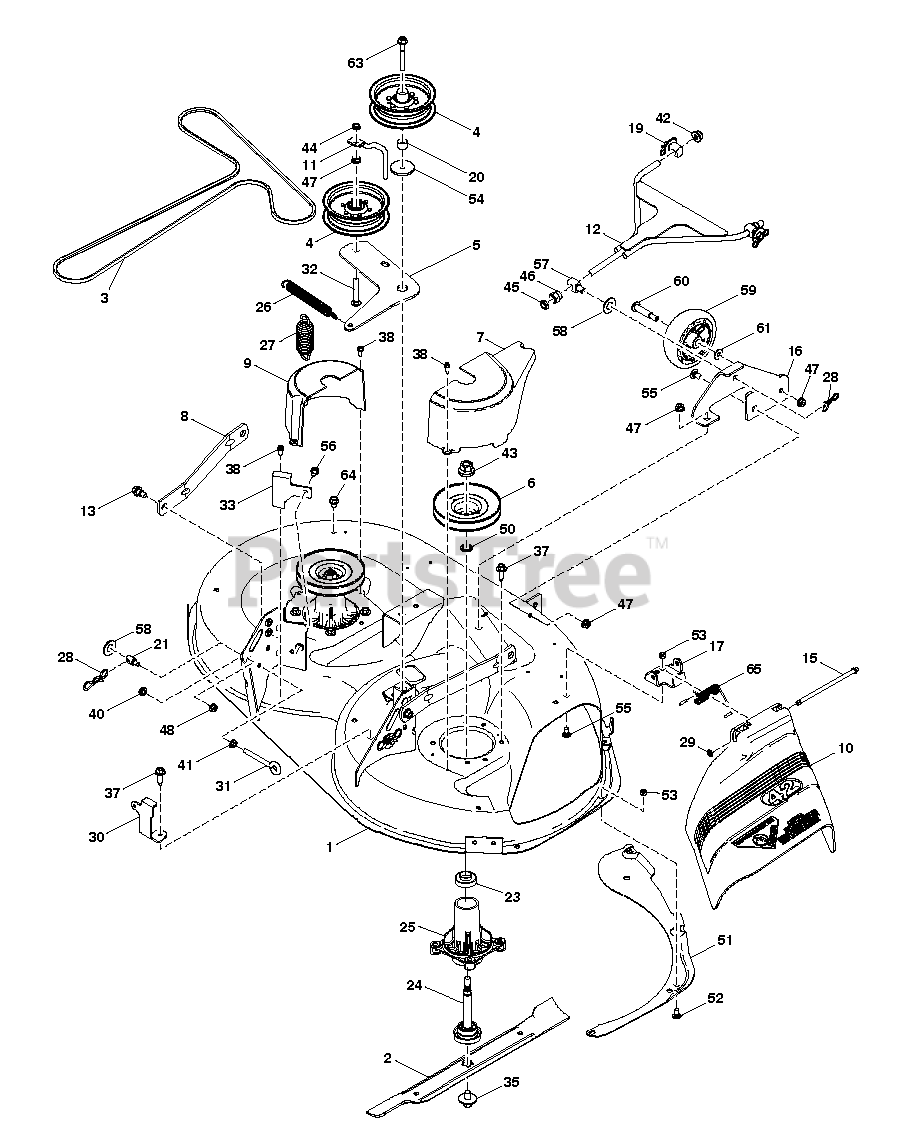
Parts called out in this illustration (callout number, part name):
1	KIT.42"DECK.W/DECALS.X668
2	42" HI-LIFT BLADE
3	BELT 42 STAMPED RZ DECK DRIVE
4	PULLEY.IDLER.2006
5	ARM 42 STAMPED RZ CLUTCHING AR
6	PULLEY.MANDREL.46"
7	COVER 42 STAMPED RZ RH MANDREL
8	ARM.RFIXED.MOWER.SUSPNSIONX431
9	COVER 42 STAMPED RZ LH MANDREL
10	SHIELD.DEFLECTOR.MOWER.42"BLAC
11	KEEPER.BELT.IDLER.54"T
12	LINK.RZ.FRONT.WELDMENT.E-DIP
13	SB 3/8-16 X 3/8 SKT HD ZD
15	ROD.HINGE
16	BRACKET.FRONT.SUSPENSION.X668
17	BRKT.DEFLECTOR.38"2005+
21	STUD.FASTNER.W/ANTI-ROTATE
23	BEARING.MANDREL.TOP.EXTENDED
24	SHAFT
25	HOUSING, MANDREL 48"
26	SPRING.MOWER.DRIVE.ELECTRIC
28	PIN.COTTER.5/16.BOW TI
29	NUT PUSH M
30	BRCKT.REAR.DECK.UPSTOP.RH.X668
31	EYE BOLT 5/16 X 3.50
32	CARRIAGE BOLT 3/8-16 X
33	BRCKT.REAR.DECK.UPSTOP.LH.X668
35	SCREW.SEMS.7/16-20X1.HEX.HEAD
37	BOLT.HEX.WASHR.HED.313-18X1.19
38	SCREW.1/4-20X5/8
40	NUT 5/16C WHIZ
41	5/16-18 NYLOC FLANGE NUT
42	7/16-14 HEX NUT W/NYL RING ZD
43	NUT.FLANGE.LOCK.TOP
45	NUT **
46	NUT, LIFT LINK 7/16-20
47	NUT LOCK FLG 3/8-16 UNC
48	NUT LOCK HEX FLANGE 5/16-18
50	WASHER.SPACER.MANDREL
51	BAFFLE DECK 42 SD BLACK
52	BOLT
53	LOCKNUT
54	SPACER.RETAINER.MOWER
56	SCREW, 3/8-16X3/4
57	SWIVEL.TRUNION.LINK.DECK.FRONT
58	WASHER
59	WHEEL.GAUGE.RALLY.NARROW
60	BOLT M
61	WASHER.5/16.FLAT.STE.STD.
63	SCREW.HXWSH.3/8
64	SCREW 3/8-16X1/2
65	SPRING.TORSION.DEFLECT
